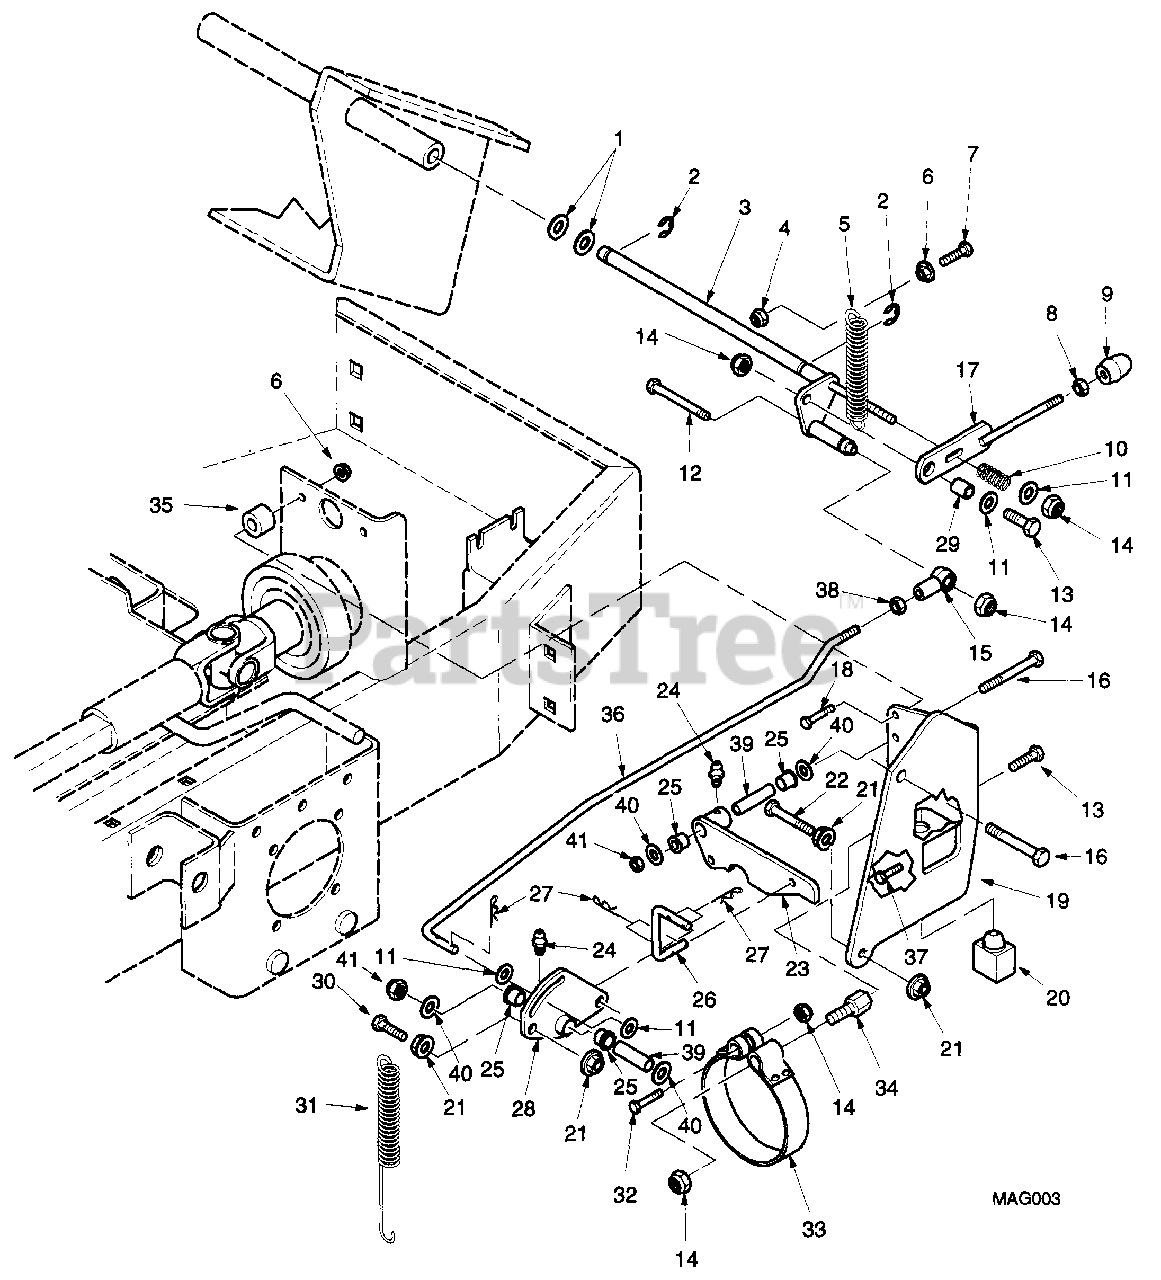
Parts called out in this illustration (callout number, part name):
1	FLATWASHER, 3/4(.766 X 1.250 X .060)
1	FLATWASHER, 3/4(.766 X 1.250 X .035)
2	RETAINING RING - .75 EXT
3	LEVER, CLUTCH ENGAGE
4	HEX LOCKNUT, ELASTIC STOP, 5/16-18
5	SPRING, CLUTCH LEVER
6	SERR. FL. HEX NUT, 5/16-18
7	SERR. FL. HEX HEAD CAPSCREW, 5/16-18 X 1
8	NUT, HEX, 3/8-16
9	GRIP, CLUTCH LEVER
10	SPRING, FRICTION CONTROL
11	FLATWASHER, 3/8(.391 X .938 X .105)
12	BOLT, HEX HEAD, 3/8-16 X 3-3/4
13	SERR. FL. HEX HEAD CAPSCREW, 3/8-16 X 3/4
14	HEX LOCKNUT, ELASTIC STOP, 3/8-16
15	BALL JOINT, RH THD, 3/8-16
16	BOLT, HEX HEAD, 5/16-18 X 2-1/2
17	LEVER, CLUTCH
18	SERR. FL. HEX HEAD CAPSCREW, 5/16-18 X 1-1/2
19	BASE, BRAKE ASSEMBLY
20	SWITCH, INTERLOCK
21	SERR. FL. HEX NUT, 3/8-16
22	BOLT, HEX HEAD, 3/8-16 X 2-1/2
23	LEVER, BRAKE ENGAGE(INCLUDES 24, 25)
24	GREASE FITTING, SHORT
25	BUSHING, OILITE - .50 I.D.
26	ROD, CLUTCH ENGAGE
27	COTTER PIN, HAIR(.080 X 1.19)
28	BELLCRANK, CLUTCH ENGAGE(INCLUDES 24, 25)
29	SLEEVE
30	BOLT, HEX HEAD, 3/8-16 X 1-1/2
31	SPRING, BRAKE
32	BOLT, HEX HEAD, 3/8-16 X 1-1/4
33	BRAKE BAND
34	ANCHOR, BRAKE
35	SPACER, BRAKE
36	ROD, CLUTCH ENGAGE
37	SERR. FL. HEX HEAD CAPSCREW, 5/16-18 X 1-3/4
38	HEX NUT, 3/8-24
39	SLEEVE, CONTROL LEVER
40	FLATWASHER, 5/16(.344 X .688 X .065)
41	HEX LOCKNUT, ELASTIC STOP, 5/16-18
